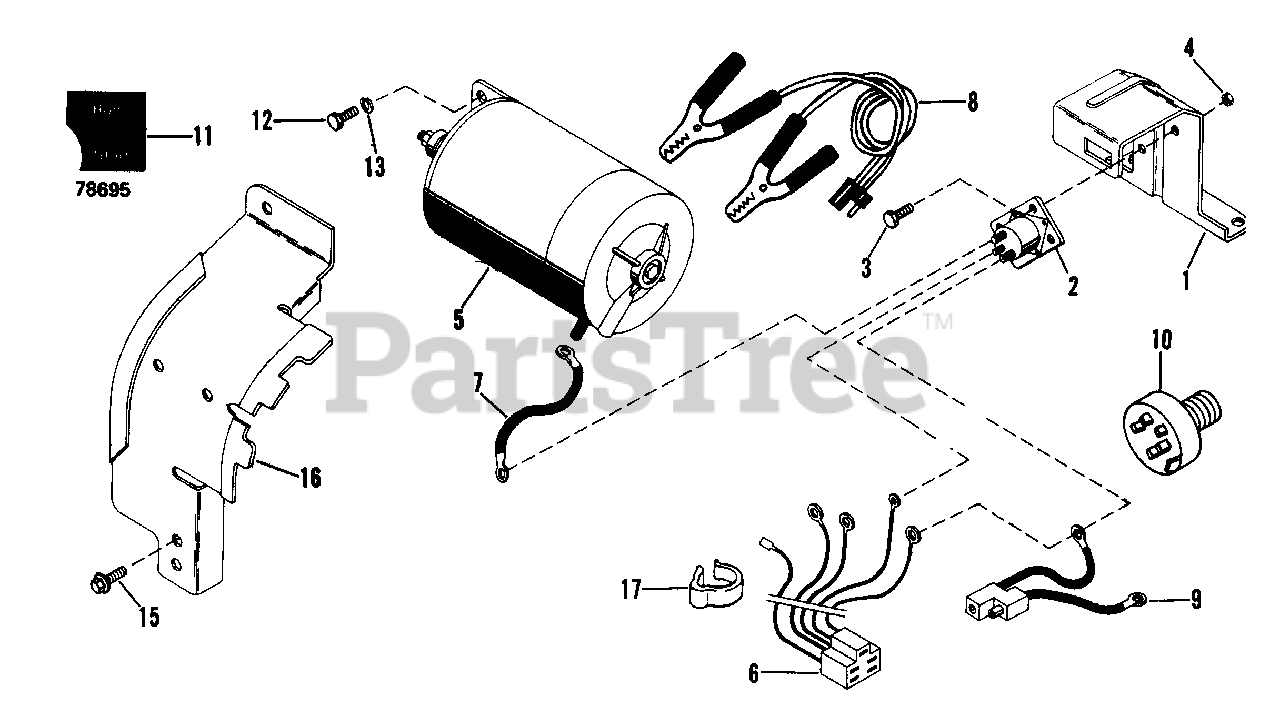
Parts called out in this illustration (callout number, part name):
1	PANEL SUPPORT
2	SOLENOID
3	BLT-HEX .25-20X.50 PL GR2
4	NUT-LK-CTR .250-20 PL
6	WIRING HARNESS
8	JUMPER CABLE W/CONNECTOR
9	ADAPTER LEAD W/CONNECTOR
10	IGNITION SWITCH ASSEMBLY
11	DECAL-SWITCH
12	BLT-HEX .31-18X.75 PL GR5
13	WASHER, HELICAL SPRING LOCK
15	SCR-TAP 8-15X.38 CR RH A
17	CONDUIT CLAMP 2 WIRE
